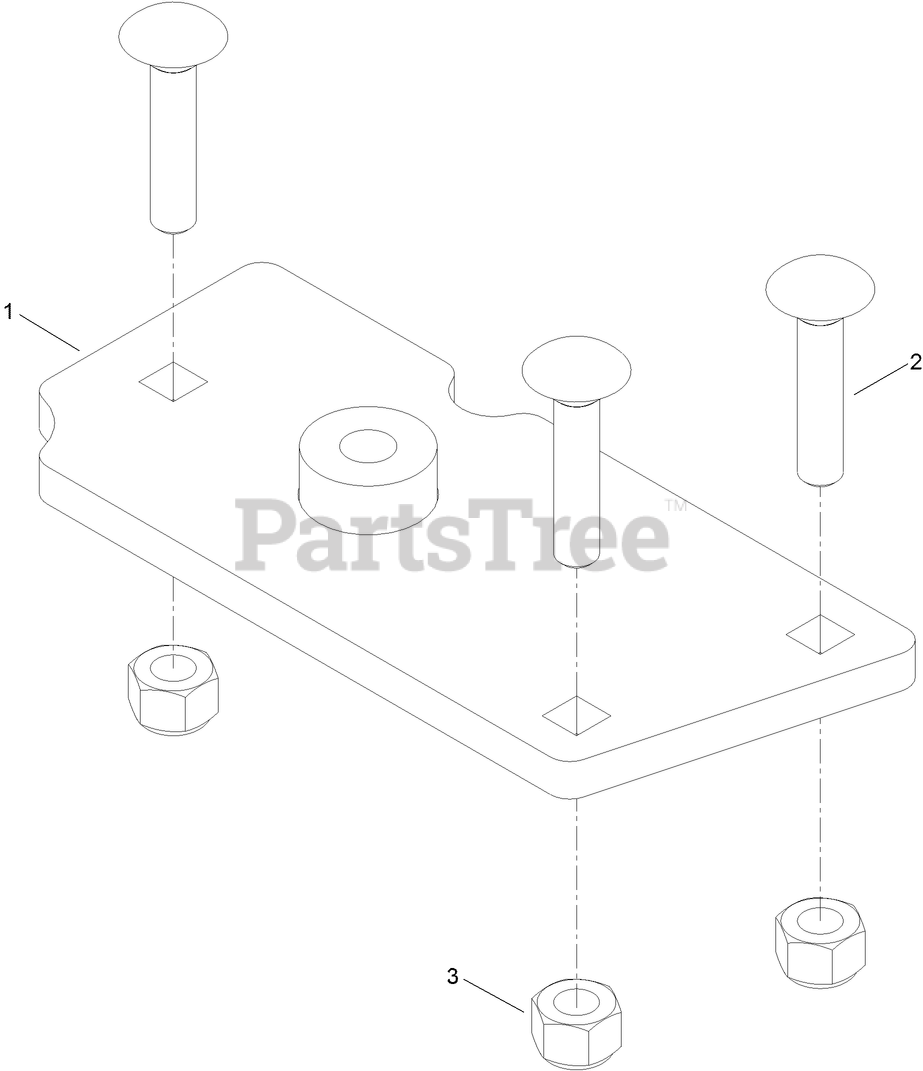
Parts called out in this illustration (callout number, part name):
1	PLATE-FRAME
2	SCREW-CARR
3	NUT-LOCK, NI
